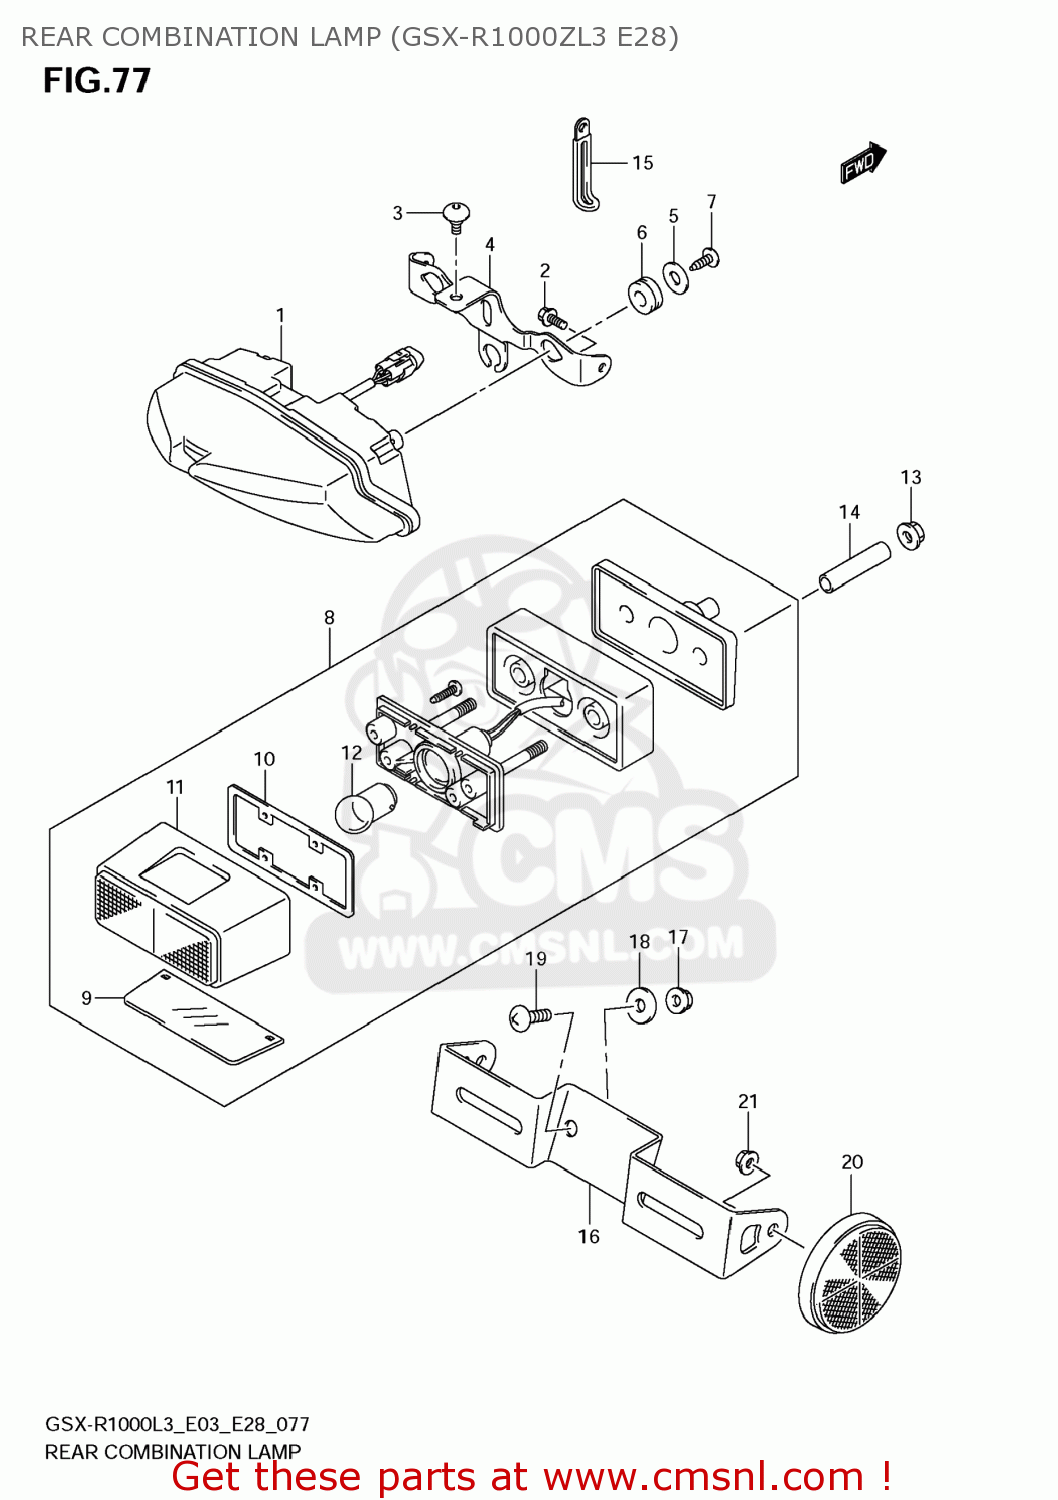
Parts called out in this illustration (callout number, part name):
1	LAMP ASSY,RR COMBINATION
2	BOLT(5X12)
3	SCREW(6X12)
4	BRACKET,RR COMBINATION LAMP
5	WASHER(5.5X20X1.2)
6	CUSHION
7	SCREW
8	LAMP ASSY,LICENSE
9	LENS,LICENSE LAMP
10	GASKET (NAS)
11	COVER,LICENSE LAMP
12	BULB(12V5W,BF150-40160A)
13	NUT
14	SPACER(6.5X9X34)
15	CLAMP(L:45)
16	BRACKET,LICENSE PLATE
17	NUT
18	WASHER(6.5X20X1.2)
19	SCREW
20	REFLECTOR ASSY,RR SIDE
21	NUT
